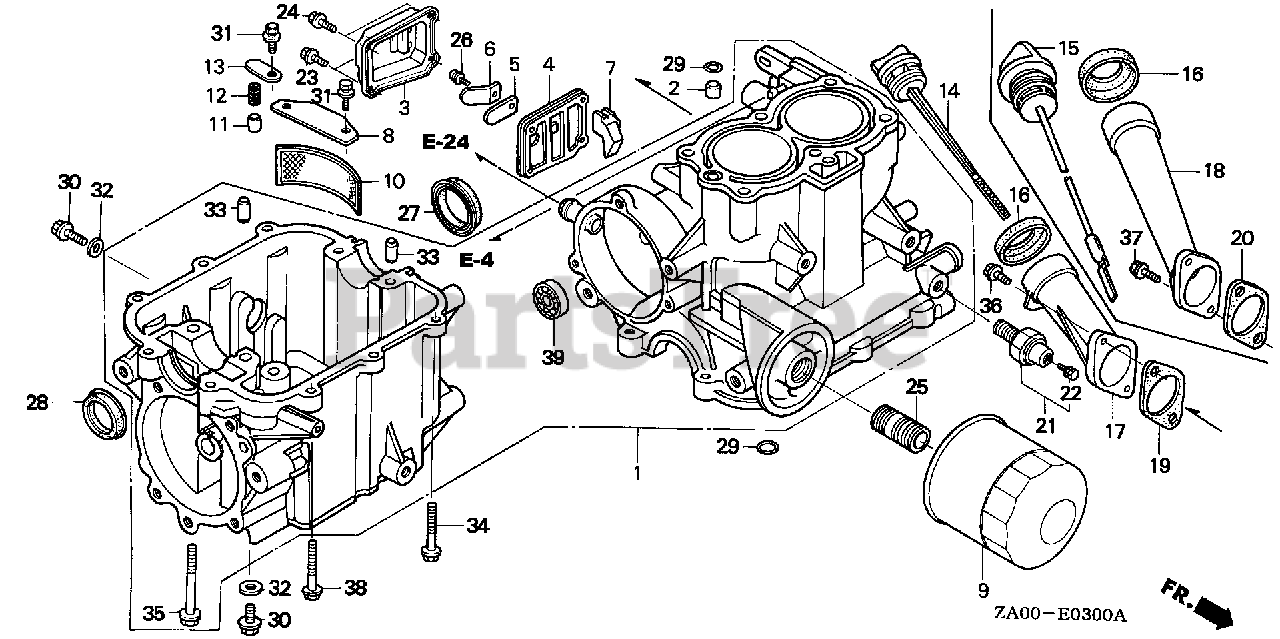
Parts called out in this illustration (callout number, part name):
1	CYLINDER ASSY.
2	ORIFICE, OIL CONTROL
3	COVER, BREATHER
4	PLATE, BREATHER
5	PLATE, VALVE
6	STOPPER, VALVE
7	GUARD, BREATHER
8	PLATE, OIL FILTER
9	FILTER, OIL
10	SCREEN, OIL FILTER
11	VALVE, CHECK
12	SPRING, VALVE
13	PLATE, VALVE
14	CAP, OIL FILLER
16	GASKET, OIL FILLER CAP
17	PIPE, OIL FILLER
19	GASKET, OIL PIPE
21	SWITCH, OIL PRESSURE
22	BOLT-WASHER (4X8)
23	BOLT, FLANGE (6X12) (CT200)
24	BOLT, FLANGE (6X14)
25	PIPE, OIL PASSAGE
26	SCREW-WASHER (5X8)
27	OIL SEAL (33X48X7)
28	OIL SEAL (30X44X7)
29	O-RING (10.8X2.4) (ARAI)
30	BOLT, DRAIN PLUG (12MM)
31	BOLT-WASHER (6X12)
32	WASHER, DRAIN PLUG (12MM)
33	PIN A, DOWEL (10X16)
34	BOLT, FLANGE (6X28)
35	BOLT, FLANGE (8X55)
36	BOLT, FLANGE (6X16) Use from Engine SN 2056820.
38	BOLT, FLANGE (6X32)
39	BEARING, RADIAL BALL (6202)
